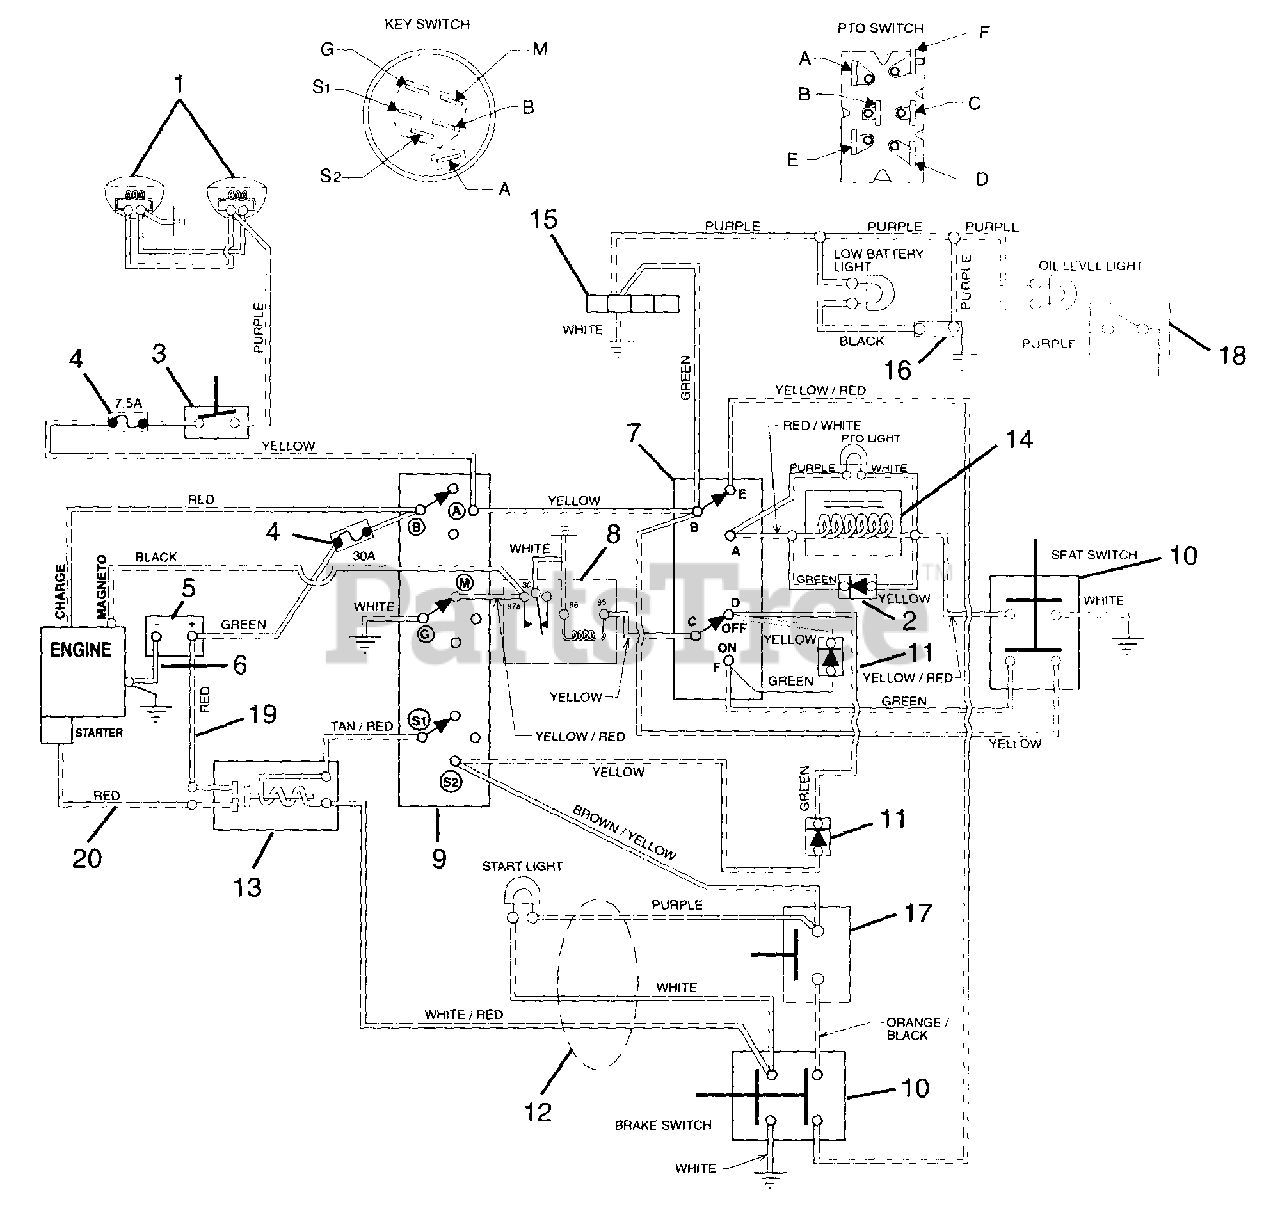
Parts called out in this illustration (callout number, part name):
1	HEADLIGHT- L.H.
1	HEADLIGHT- R.H.
2	DIODE & HOUSING
3	LIGHT SWITCH
4	7.5 Amp Fuse
4	30 Amp Fuse
5	BATTERY W/TUBE
6	GROUND CABLE .31X22.00X.31
7	SWITCH ASSEMBLY- PTO
8	RELAY
9	KEY SWITCH
10	SWITCH- DOUBLE POLE N.O./N.O.
11	MOLDED DIODE PLUG 1 AMP
12	WIRE HARNESS- YT15G
13	SOLENOID
14	ELECTRIC CLUTCH/BRAKE(1.8AMP)
15	HOUR METER W/ LEADS
16	VOLTAGE SENSOR
17	SWITCH, NEUTRAL START N.C.
18	OIL SENSOR- FASCO #0454-0513
19	START CABLE 22"
20	STARTER CABLE 6.75"
